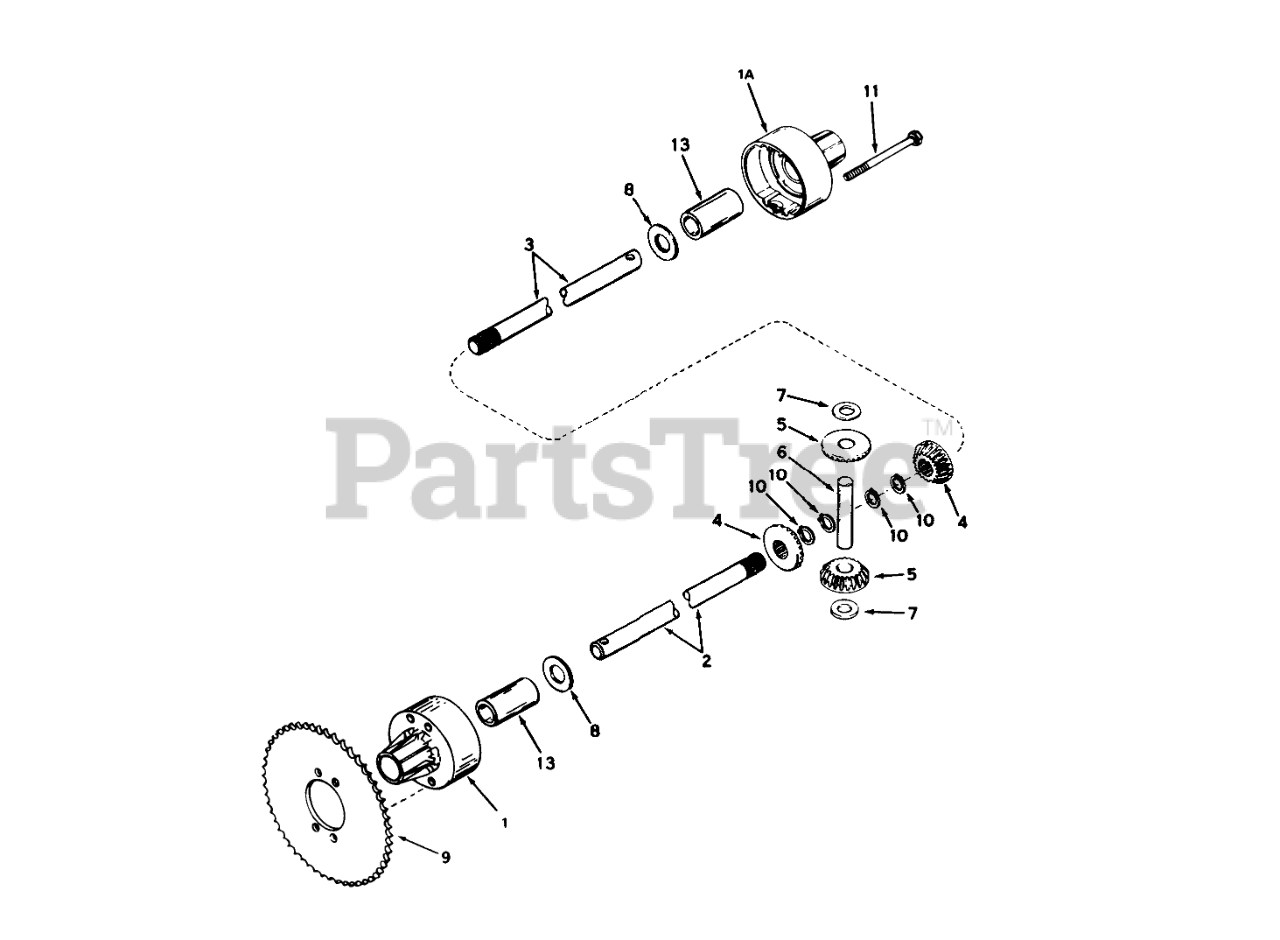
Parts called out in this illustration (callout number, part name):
1	Housing-Differential Carrier (Incl. #13)
1A	Housing-Differential Carrier (Incl. #13)
2	Axle (10-1/4" long)
3	Axle (18-7/8" long)
4	Gear Bevel
5	Gear Pinion
6	Pin Drive
7	Washer Thrust
8	Washer
9	Sprocket (See "Sprocket Chart" for optional sprocket)
10	Retaining Ring (pkg of 2)
11	Screw-Hex Hd.
13	Bushing
